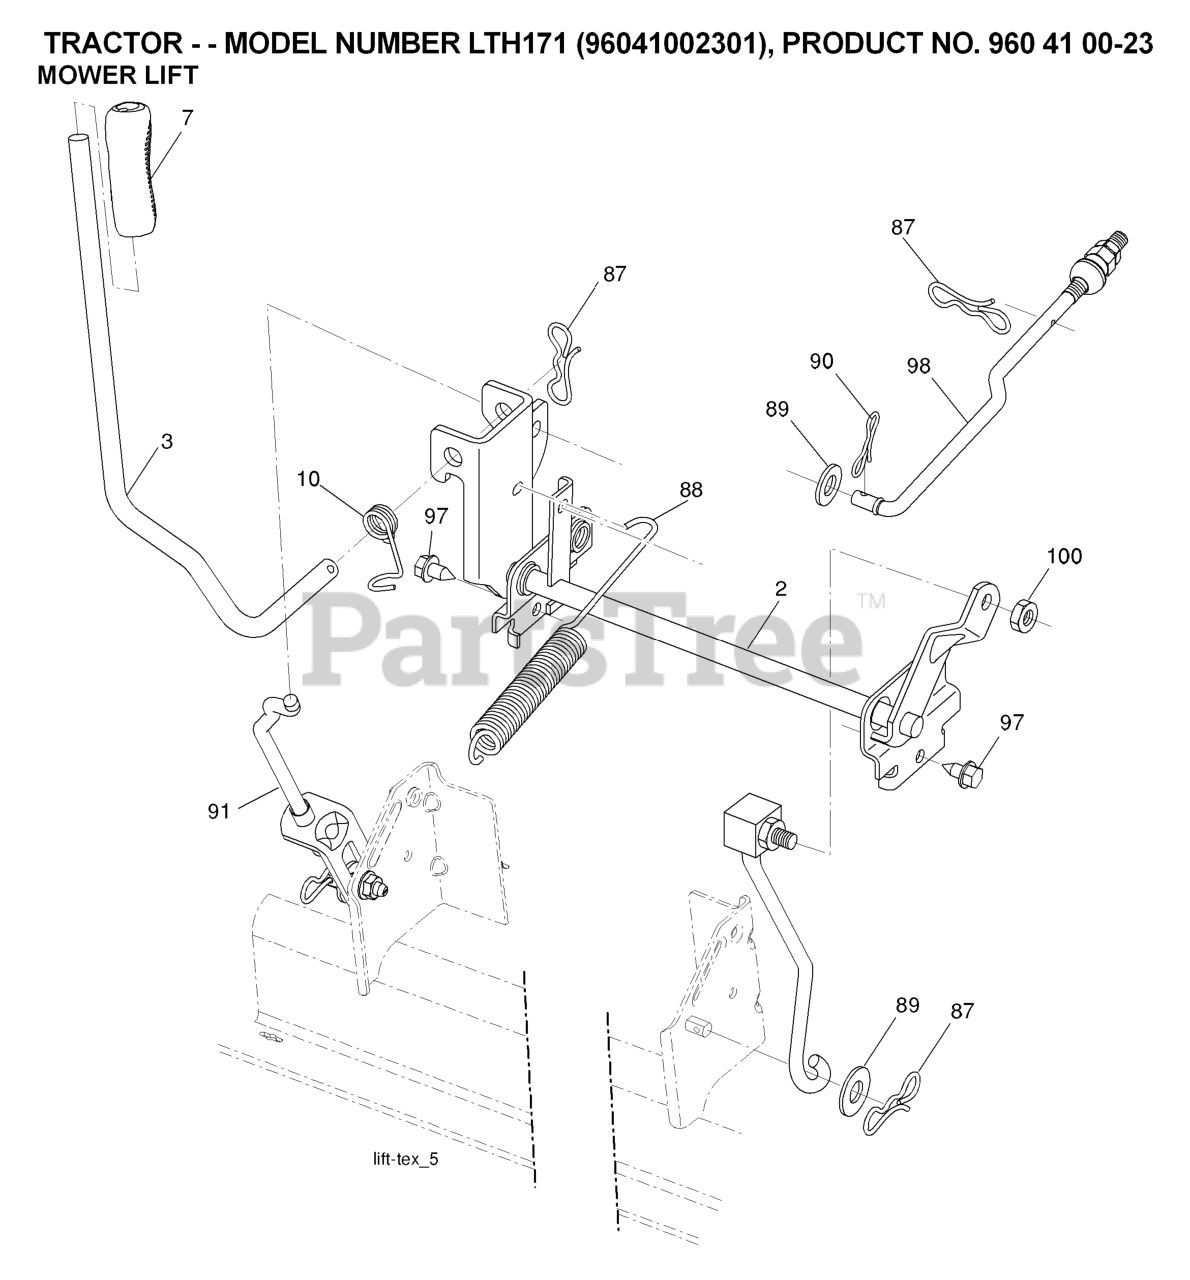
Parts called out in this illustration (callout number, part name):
1	BAIL GROUND DRIVE
2	SHAFT.ASM.LIFT.CROSS.H
2	HCS, M6-1.0 X 70, GR8.8
3	LEVER.LIFT.HANDLE.LT
3	HCS, M6-1.0 X 50, GR8.8
4	WASHER, 5/16, WAVE
5	GRIP, FOAM (GROUND) 15
7	GRIP.HANDLE.LIFT.PVC.BLACK
7	ROPE GUIDE
8	DECAL, STOP SIGN
9	DECAL, PTO
10	SPRING.TORSION.LIFT.HANDLE
10	CABLE, GROUND DRIVE
11	THROTTLE CABLE, BBC
12	BBC CONTROL
14	SCREW 3/8C X 3/4 HEX CAP
15	NUT.1/4-20.HEX.NYLOC.ZD
16	NUT 3/8-16 NYLOC
87	PIN.COTTER.7/16.BOW TI.
88	SPRING.LIFT.ASSIST
89	WASHER.CLEAR.ZINC
90	PIN.COTTER.5/16.BOW TI
91	LINK.ASM.LIFT.REAR
97	SCREW, 3/8-16X3/4
98	LINK.ASM.SUSP.FRONT.MW
100	LOCKNUT
